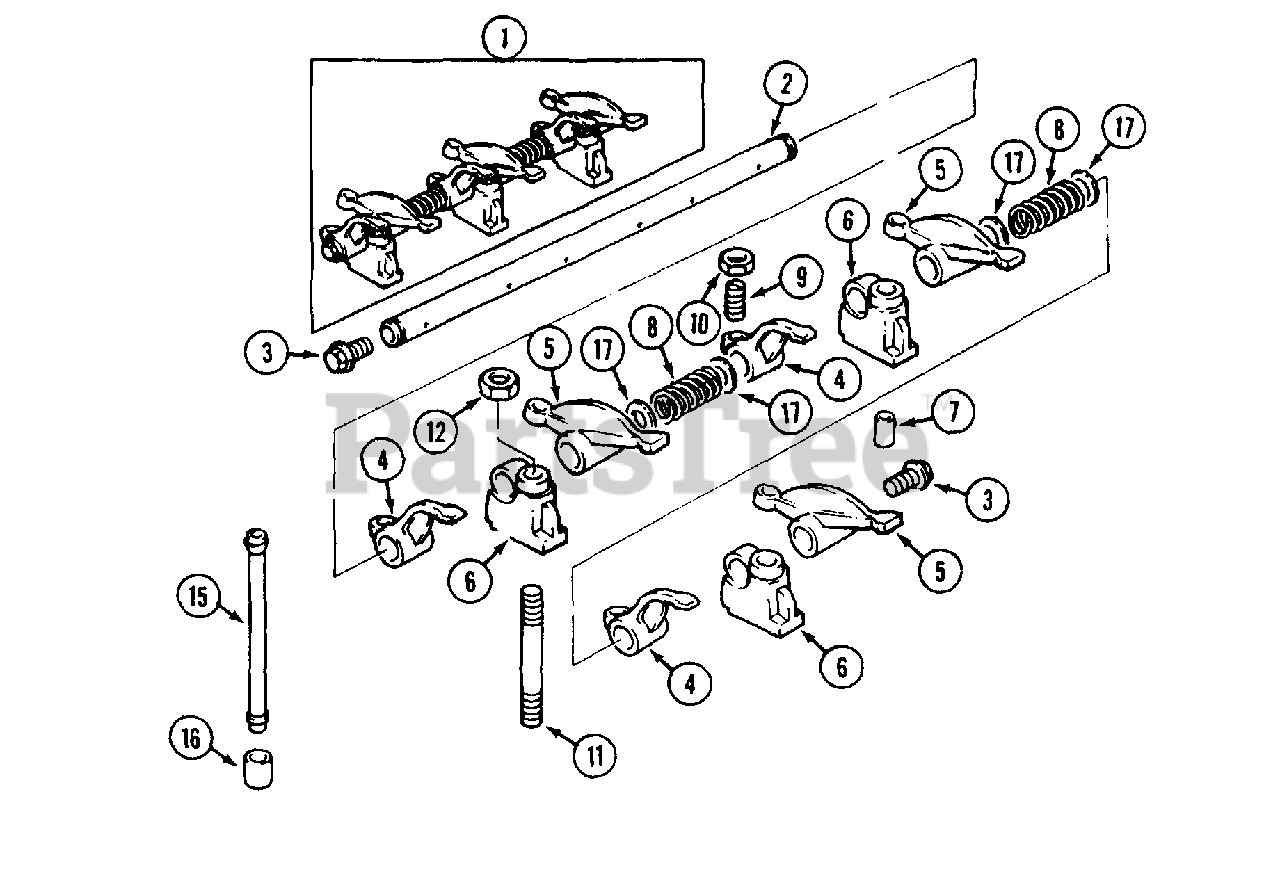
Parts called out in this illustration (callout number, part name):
1	SHAFT ASSEMBLY - rocker
2	SHAFT
3	PLUG
4	LEVER - L.H.
5	LEVER - R.H.
6	BRACKET
7	PIN
8	SPRING
9	SCREW - adjusting
10	NUT
11	STUD
12	NUT
15	ROD
16	TAPPET
17	WASHER
